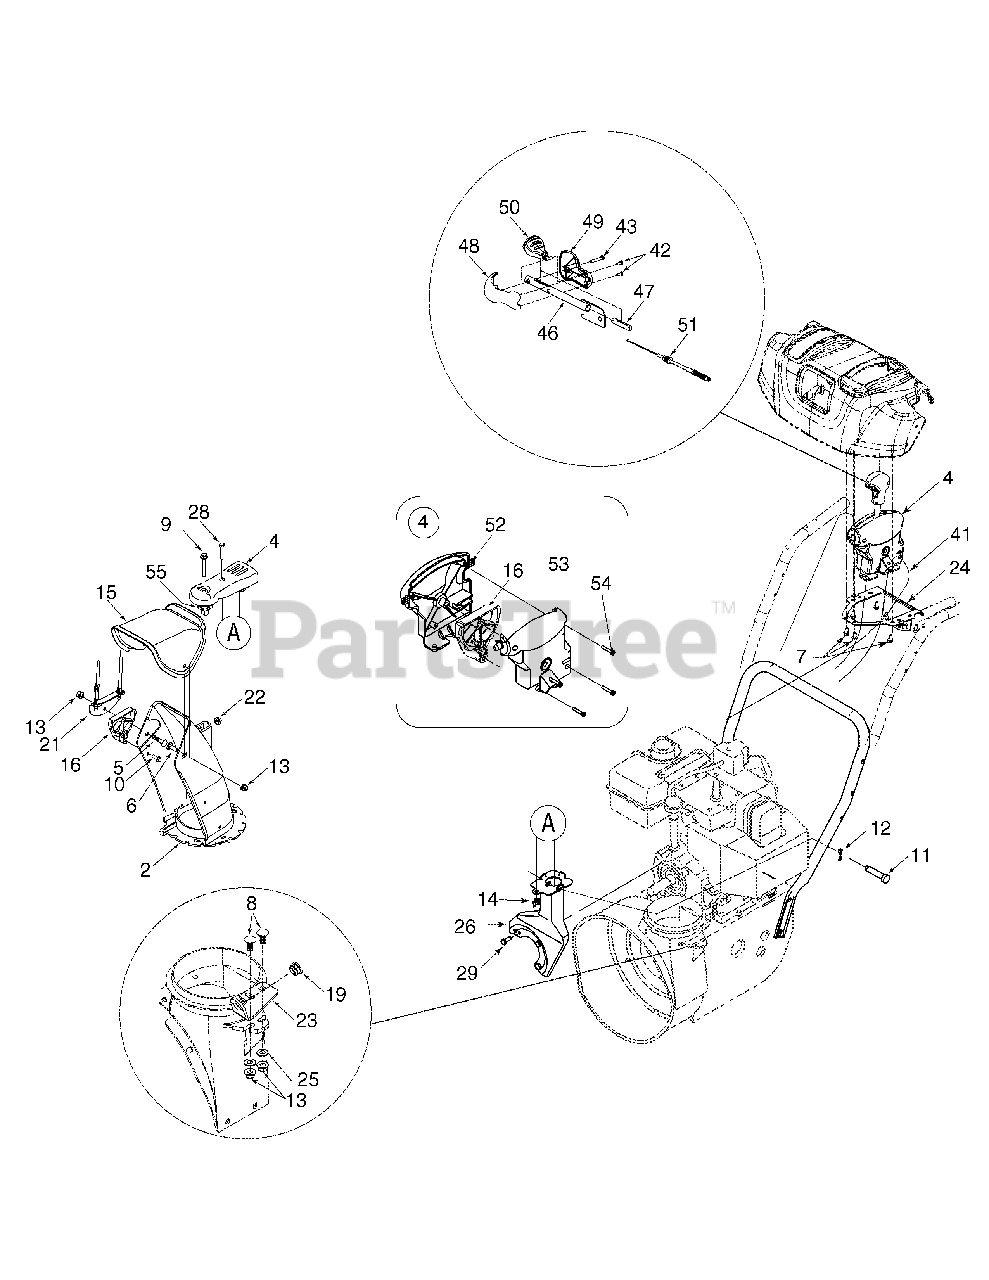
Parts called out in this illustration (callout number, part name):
2	Lower Chute (4 Way)
4	4 Way Chute Control Assembly Service Kit
5	Carriage Bolt 5/16-18 x 1.50 Gr. 2
6	Carriage Screw 5/16-18 x 1.0
7	Hi-Lo Screw 1/4-15 x .5
8	Carriage Bolt 5/16-18 x 1.00" Lg
9	Shoulder Screw .312 x 1.7:1/4-20
10	Hex Tapp Scr 1/4 x .75" Lg.
11	Clevis Pin 3/8 x 1.87
12	Bow Tie Cotter Pin
13	Flange Locknut 5/16-18 Gr. F Nylon
14	Wing Nut 1/4-20
15	Upper Chute w/Export Label, Remote
16	Cable Guide
19	Plastic Bushing .380 ID
22	Hex L-Flanged Nut 1/4-20 Gr. F Nylon
25	Flat Washer .349 ID x .879 OD x .063
26	Support Bracket
27	Hi-Lo Screw 1/4-15 x .50
28	Hex Hd. Cap Screw 1/4-20 x 1.5 Gr. 5
29	Hex Hd. Cap Screw 5/16-24 x .75
41	Chute Rotation Cable
42	Plastite Screw #6 x .375
43	Plastite Screw #8 x 1.00
46	Tube & Brkt. Lever Ass'y
47	Plunger
48	RH Trigger Control Knob
49	LH Trigger Control Knob
50	Trigger Levier
51	Detent Cable
52	Control Head Housing LH
53	Control Head Housing RH
54	Screw #8 x 1.0 Plastite
